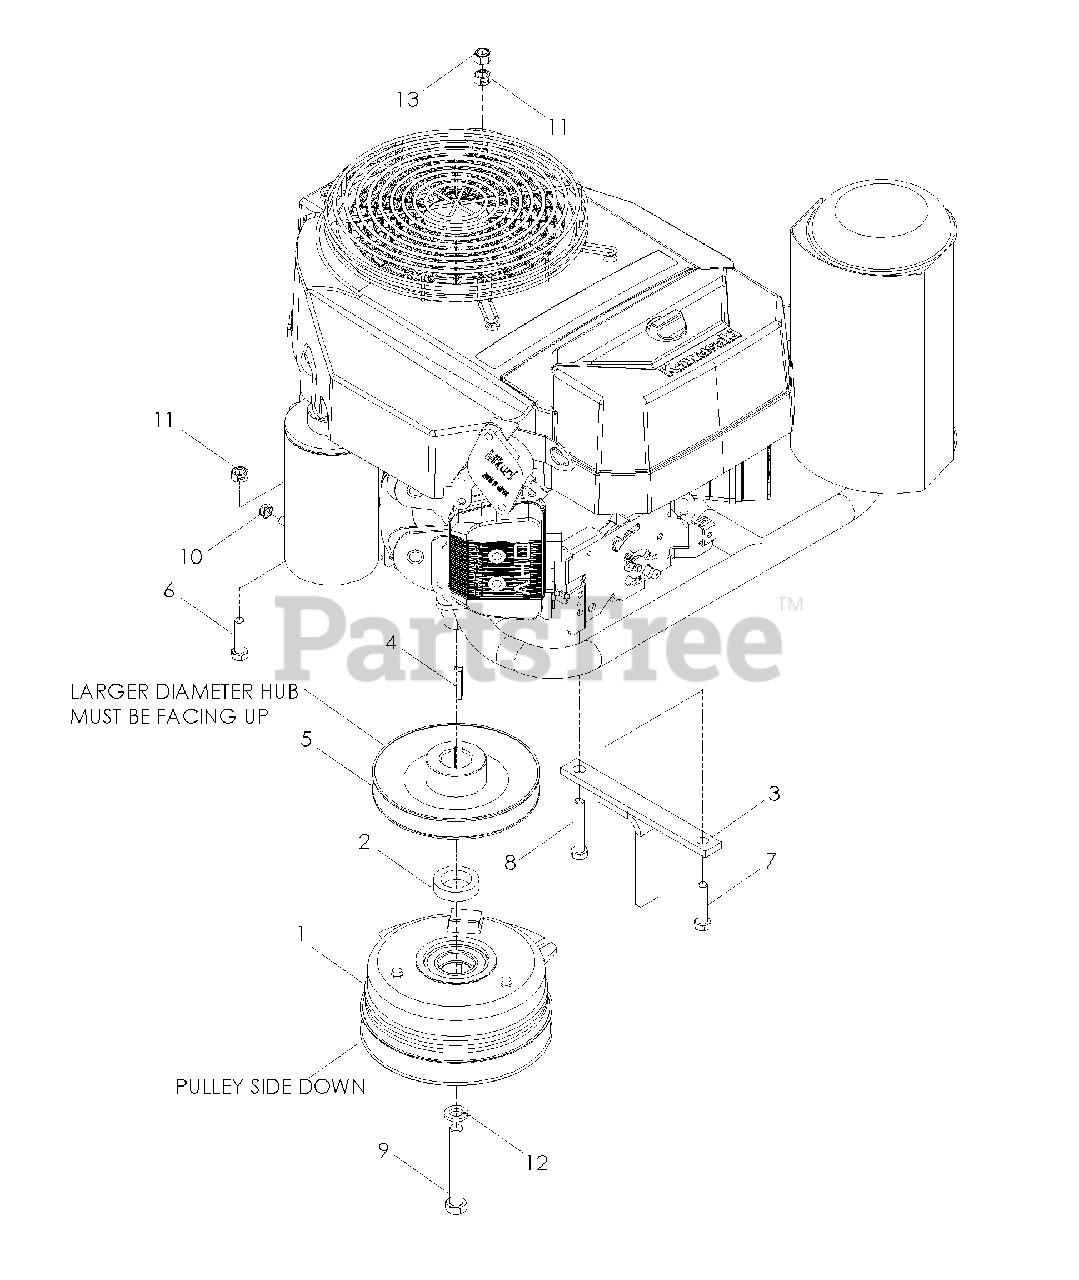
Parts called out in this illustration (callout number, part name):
1	CLUTCH, 125 FT/LBS
3	TIE DOWN, CLUTCH
4	KEY1/4 SQ x 1 1/8
5	PULLEY, PUMP
6	HCS 5/16-18 x 1 1/4
7	HCS 5/16-18 x 1 1/2
8	HCS 5/16-18 x 2
9	HCS 7/16-20 x 3
10	NUT 1/4-20 THIN NYLOC
11	NUT 5/16-18 HEX CTRLK
12	WASHER 7/16 SLW
13	NUT 5/16-18 HEX NYLOC
